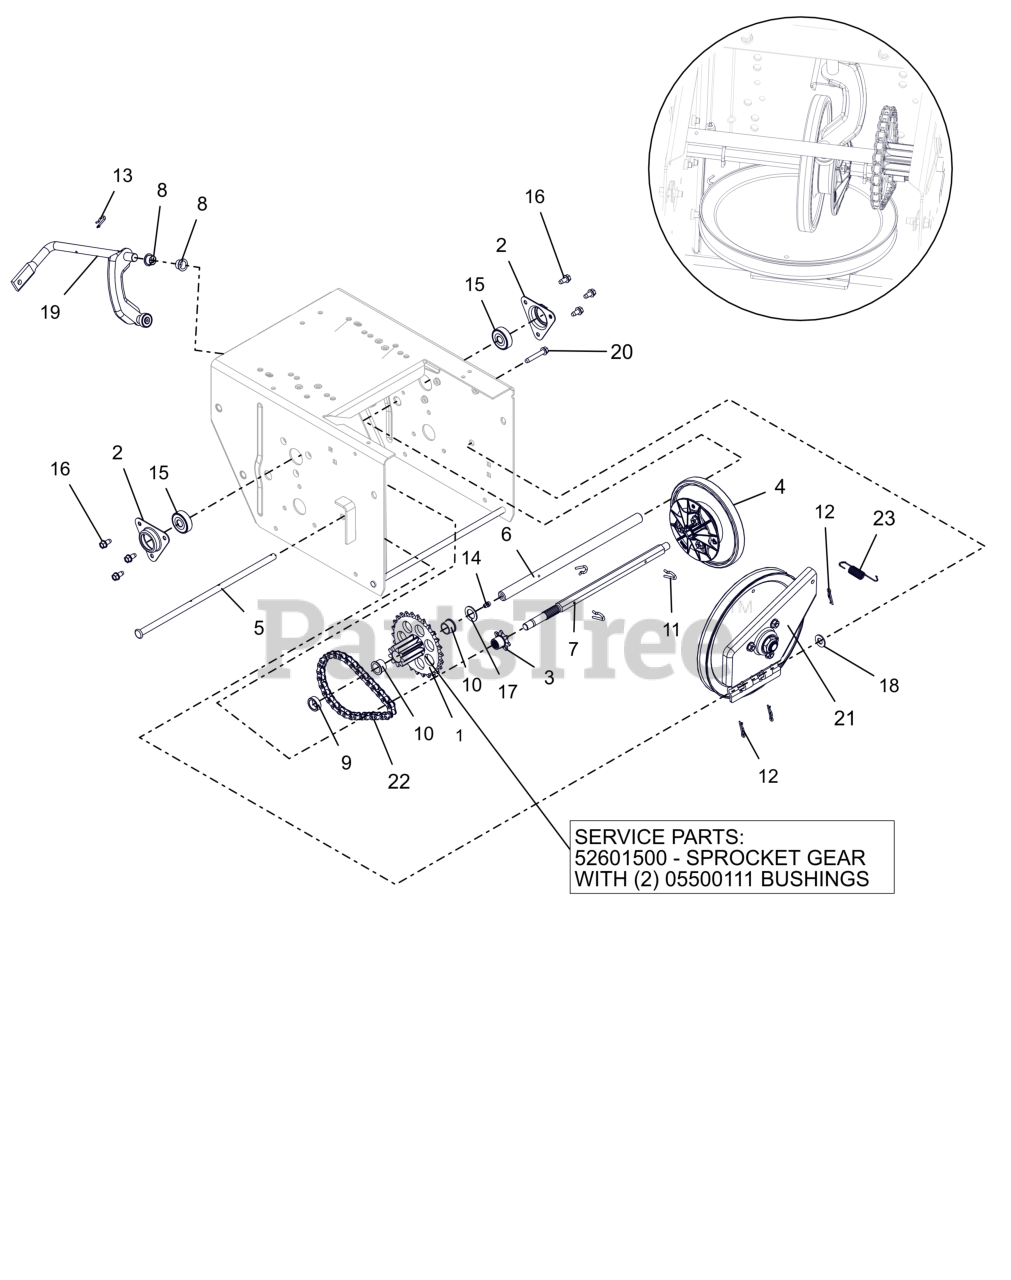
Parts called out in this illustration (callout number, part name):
1	PINION & SPROCKET
1	PINION & SPROCKET W/BUSHINGS
2	FLANGE, BEARING
3	SPROCKET, PINION 7T W/SPLINE
4	DISC, FRICTION DRIVE-ASSEMBLY
5	PIN, PIVOT
6	SHAFT, PINION
7	SHAFT, HEX
8	BUSHING, POLYLINER-.50 SPLIT
9	BSHG-SLV, .635X.880X.305
10	BSHG-FLG .625X.750X.500X.875
11	PIN, SPRING CLIP
12	PIN, HAIR #225 .072X1.09
13	CLIP, SPRING
14	ZERK,FITTING .25X.125 DRIVE IN
15	BRG-BALL .437X1.375X.437
16	SCR-TAP .25-20X.50 HWH ZCC
17	WSHR, FLT .630X1.005X.062 ZCC
18	WSHR,FLT .406X.812X.065 ZCC
19	ARM, SHIFT - ASSEMBLY
20	SCR,TAP .25-20X1.50 HWH TR ZCC
21	PLATE, SWING ASSEMBLY-DEEP
22	CHAIN - #41, 32 PITCHES
23	SG-TENS .048X.50X2.8
